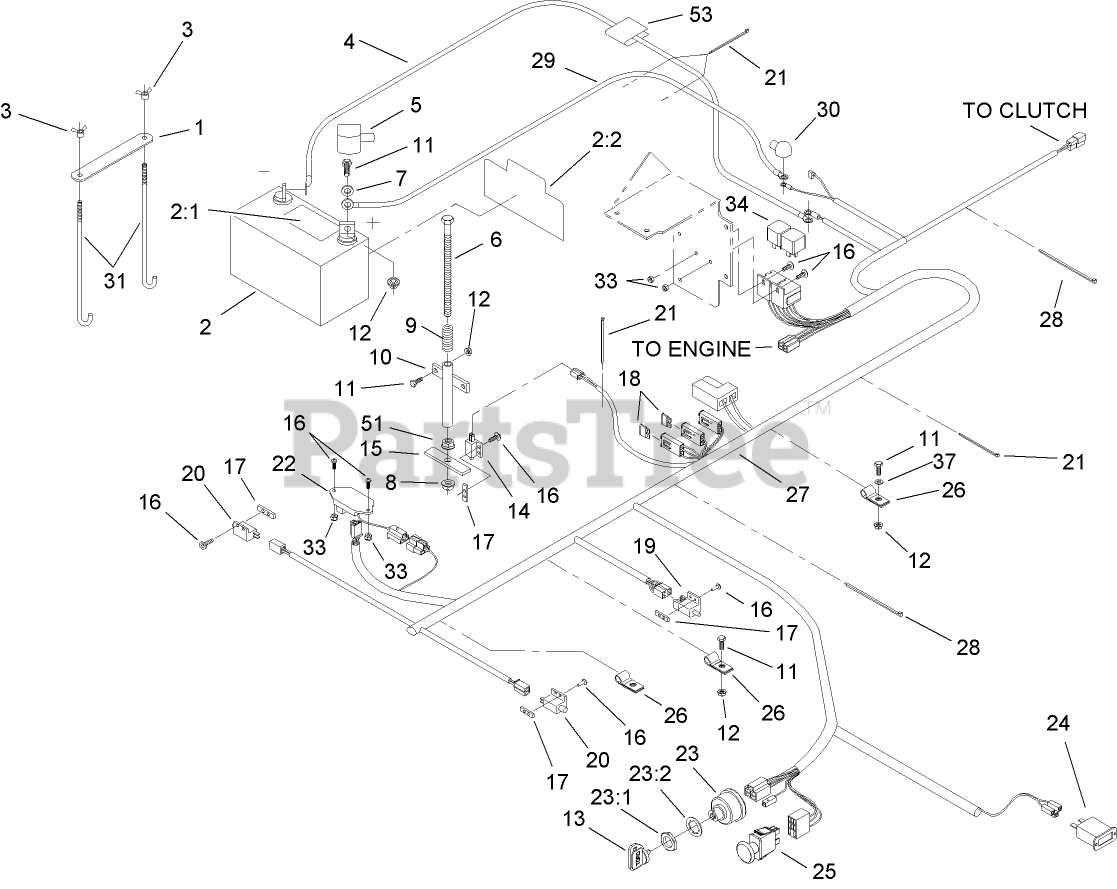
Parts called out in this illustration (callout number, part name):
1	STRAP-HOLDDOWN, BATTERY
2	BATTERY
2:1	Decal-Battery
2:2	Decal-Battery
3	WINGNUT
4	WIRE-GROUND
5	INSULATOR-BATTERY
6	SCREW-HH
7	WASHER-FLAT
8	NUT-LOCK, NI
9	SPRING-SWITCH, SEAT
10	MOUNT-SPRING, SEAT
11	SCREW-HH
12	NUT-HF
13	KEY-IGNITION
14	SWITCH-CLOSED, NORMALLY
15	PLATE-SWITCH, SEAT
16	SCREW-PPH
17	PLATE-TAPPED
18	FUSE-BLADE TYPE, 20 AMP
19	SWITCH
20	SWITCH-OPEN, NORMALLY
21	TIE-CABLE
22	MODULE-DELAY, SEAT
23	SWITCH ASM
23:1	NUT-HH
23:2	WASHER-TOOTH, INTERNAL
24	METER-HOUR
25	SWITCH-PTO
26	CLIP-LOOM
27	Harness-Wire
28	TIE-PLASTIC
29	WIRE-STARTER
30	INSULATOR-SOLENOID
31	BOLT-HOLDDOWN
33	NUT-LOCK, NI
37	WASHER-FLAT
51	NUT-HEX
53	DECAL-INSTRUCTIONS, CHARGING
